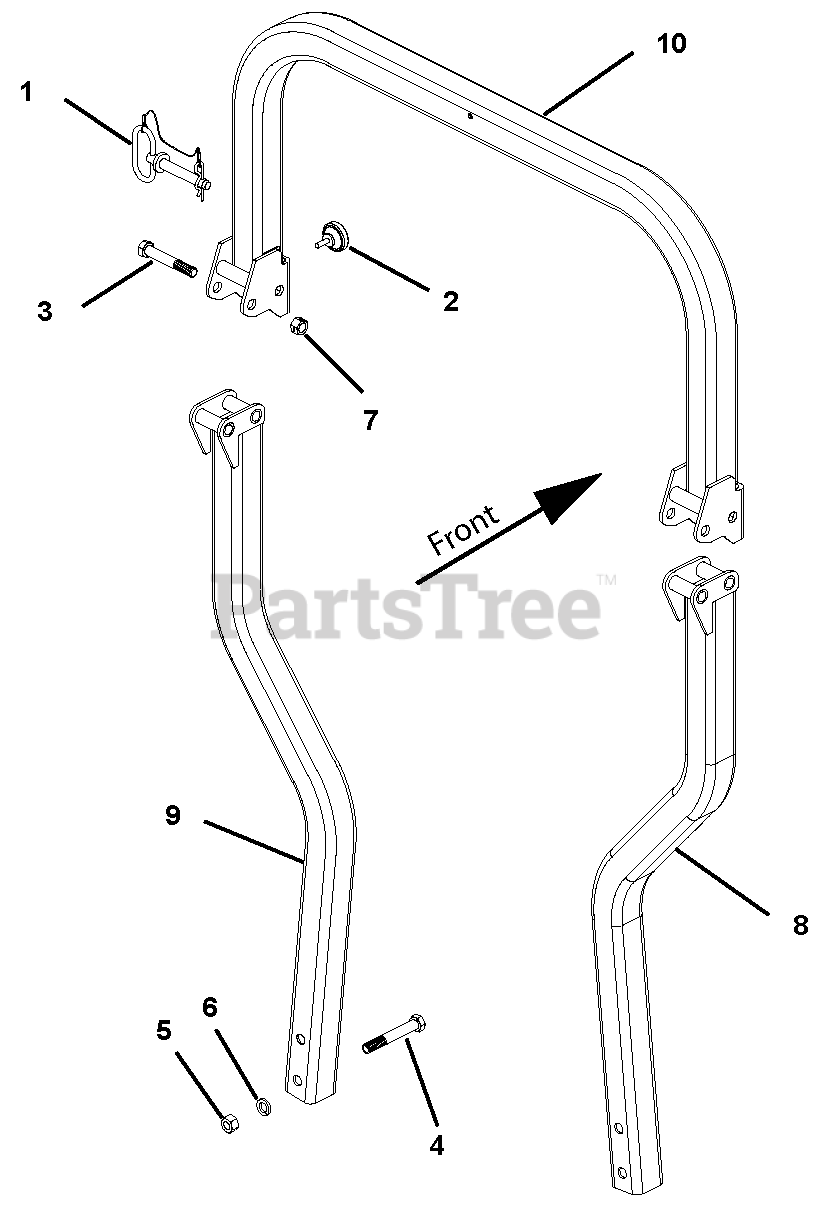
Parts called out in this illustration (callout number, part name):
1	ROPS Lock Pin Assembly
2	5/16 x 3/4" Round Knob
3	1/2 x 3-1/4" Hex Bolt
4	1/2 x 3-1/2" Hex Bolt
5	1/2" Hex Nut
6	1/2" Spring Lock Washer
7	1/2" Center Lock Nut
8	Right Side Base Weldment
9	Left Side Base Weldment
10	Center Tube Weldment
